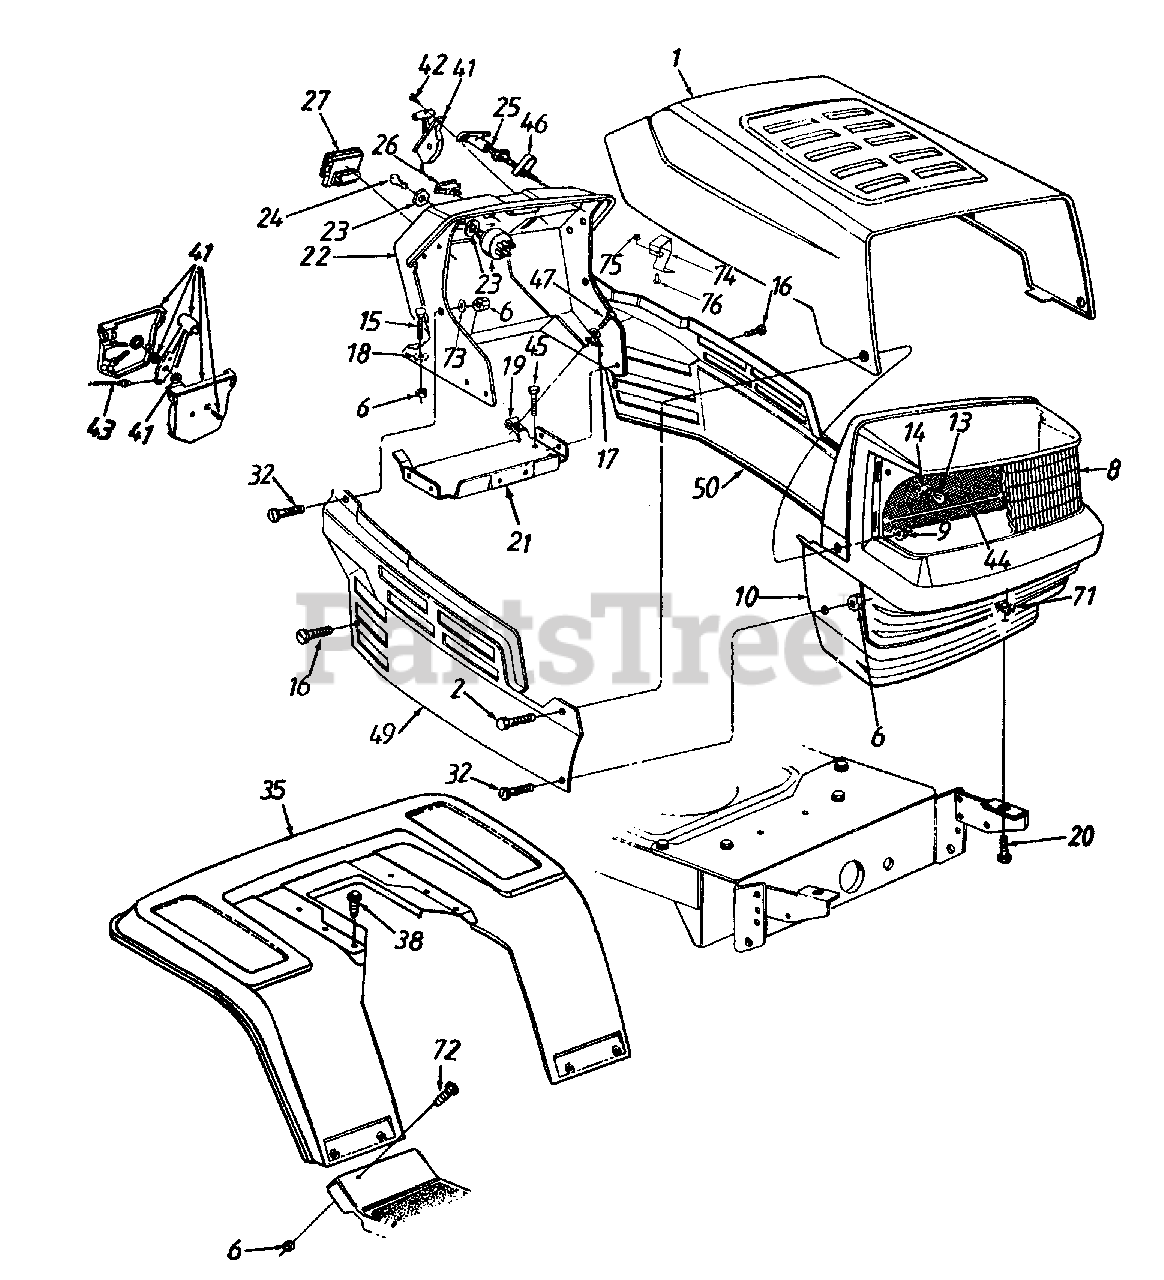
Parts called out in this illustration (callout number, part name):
6	Hex Sems Nut 1/4-20 Thd.
8	Headlight Lens w/o Logo
9	Flange L-Nut l/4-20 Thd.
10	Grille
13	Lamp
14	Socket
15	Carriage Bolt 1/4-20 x .75" Lg.
16	Hex Wash. Hd. TT-Tap Scr.1/4-20 x .5" Lg.
17	Fl-Wash..281" I.D. x .73" O.D.
18	Bolt Retainer 1/4" I.D.
19	Speed Nut 1/4-20Thd.
20	Hex Bolt 5/16-18 x .75" Lg.
23	Ignition Switch
24	Ignition Key
25	Choke Control 23" Lg.
26	Light Switch
27	Ammeter
32	Truss Mach. Scr. 1/4-20 x .5" Lg.
41	Throttle Box Ass'y.
42	Truss Mach. AB-Tap Scr.#10 x .5" Lg.
43	Throttle Control Wire 18.5" Lg.
44	Grille Reflector Label
45	Hex Wash. Hd. B-Tap Scr.5/16-18 x .5" Lg.
46	Choke Retainer
47	Hex TT-Tap Scr. 1/4-20 x .75" Lg.
72	Truss Mach. Scr. 1/4-20 x .5" Lg.
73	Fl-Wash..283" I.D. x .75" Lg.
74	Hood Latch
75	Hex Sems Nut 10-24 Thd.
76	Truss Mach. Scr. 10-24 x .5" Lg.
